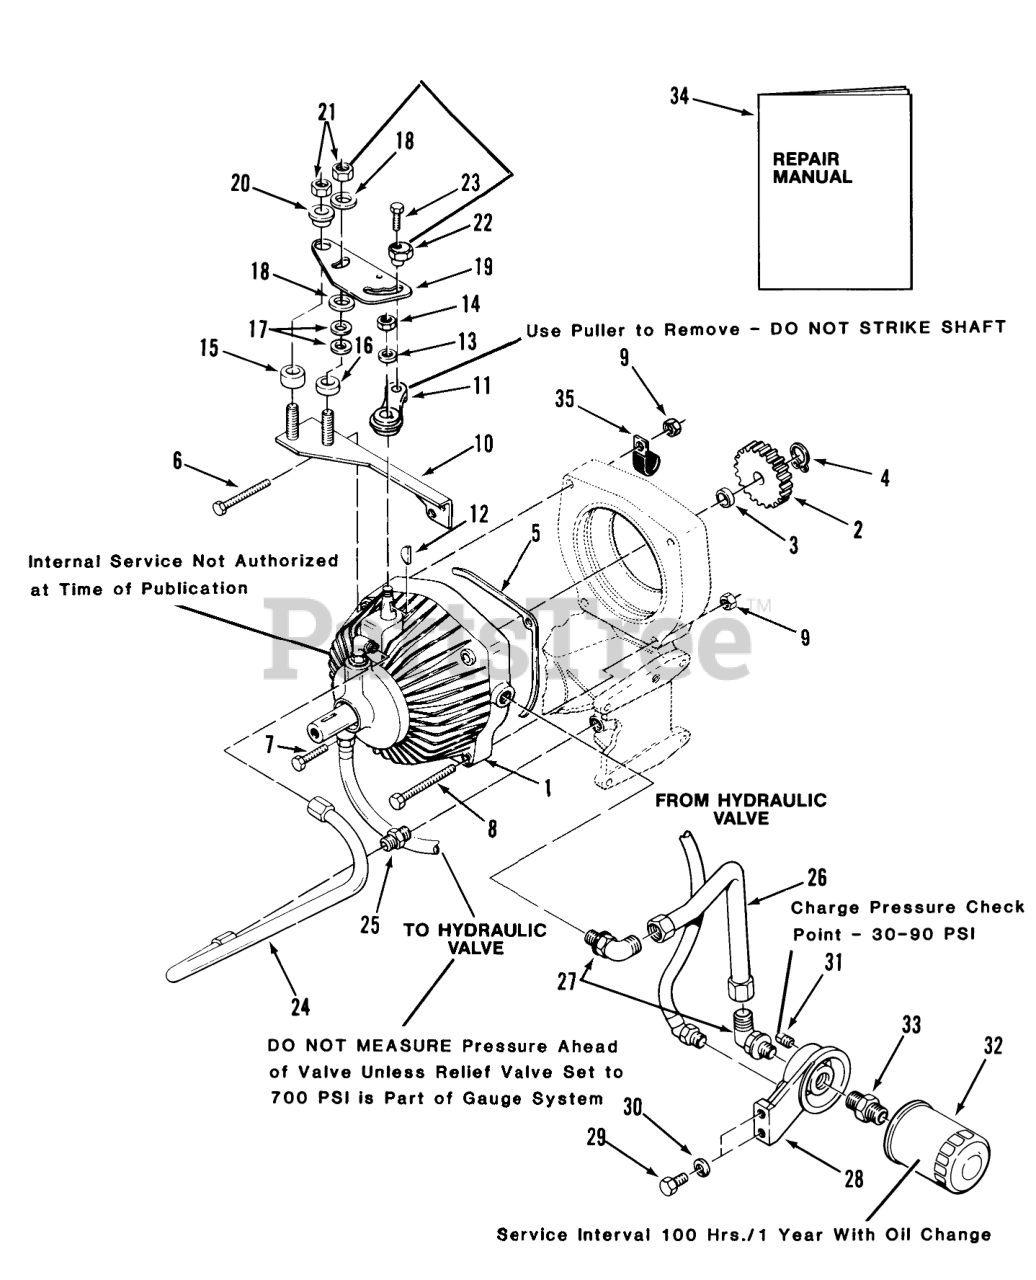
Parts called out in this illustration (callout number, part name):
1	Pump & Motor
2	GEAR 20 TEETH DRIVE
3	SPACER GEAR
4	SNAP RING- 5/8 EXT
5	GASKET
6	H H C S
7	Bolt
8	Bolt 3/8-16 x 6 1/2
9	Nut
10	ASSY-PLATE B
11	ARM-SPEED CONTROLB
12	Key #5 Woodruff
13	Washer
14	Eslok Nut
15	SPACER-PIVOT
16	SPACER-FRICTION
17	WASHER-SPRING DISC
18	FRICTION WASHER
19	CAM-SPEED CONTROL (NS)
20	CAM-SPACER
23	Bolt
24	ASSY-TUBE-SUCTION
25	FITTING-TUBE
26	Tube Assembly
27	Elbow (With 973370 O-Ring)
28	BASE-FILTER
29	Bolt
30	Lockwasher
31	PLUG 1/4 PIPE ALLEN
32	Filter-Oil
33	FITTING
34	Repair Manual
35	CLIP
